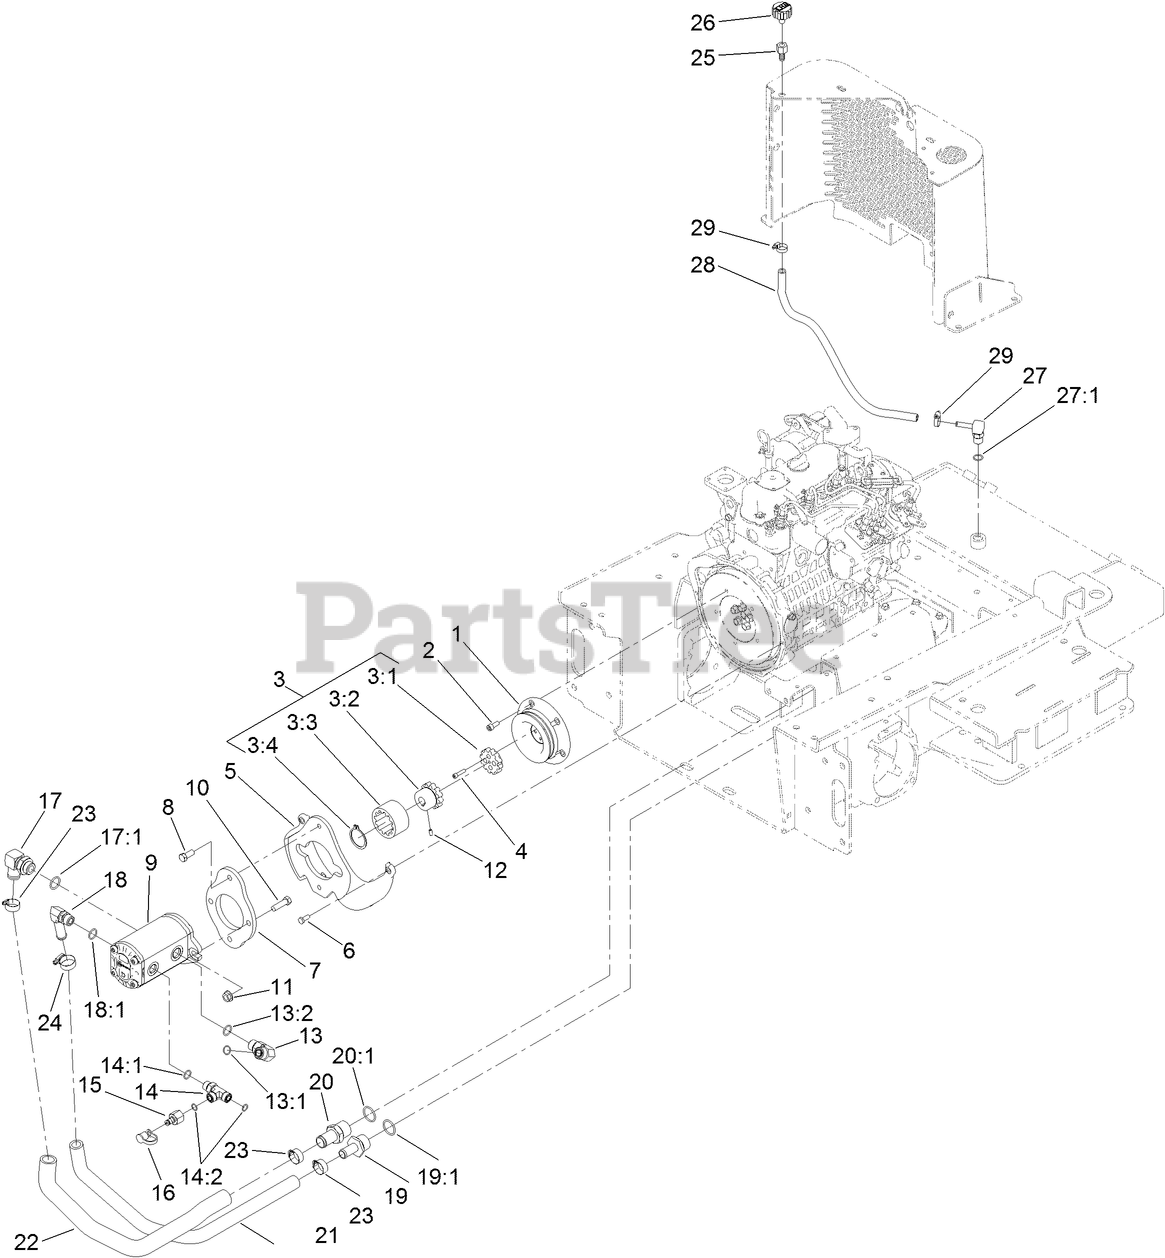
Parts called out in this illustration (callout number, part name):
2	SCREW-CAP, HSH
3	COUPLING ASM
3:1	HUB-COUPLING
3:2	SLEEVE-HUB
3:3	SLEEVE-COUPLING
3:4	RING-SNAP, COUPLING
4	SCREW-HSH
5	PUMP-MOUNT
6	SCREW-HH
7	PLATE-MOUNT, PUMP
8	SCREW-HH
9	PUMP-HYD
10	SCREW-HH
11	NUT-HF
12	SCREW-SET, HSH
13	FITTING-ELBOW, 90 DEG
13:1	O-RING
13:2	O-RING
14	FITTING-TEE
14:1	O-RING
14:2	O-RING
15	FITTING
16	CAP-DUST
17	FITTING-90
17:1	O-RING
18	FITTING-90
18:1	O-RING
19	FITTING-STR
19:1	O-RING
20	FITTING-STR
20:1	O-RING
21	HOSE-FORMED, SUCTION
22	HOSE-FORMED, SUCTION
23	CLAMP-HOSE
24	CLAMP-HOSE
25	FITTING-FEMALE, BARBED
26	BREATHER
27	FITTING-90
27:1	O-RING
28	HOSE-DRAIN, ENGINE OIL
29	CLAMP-HOSE
